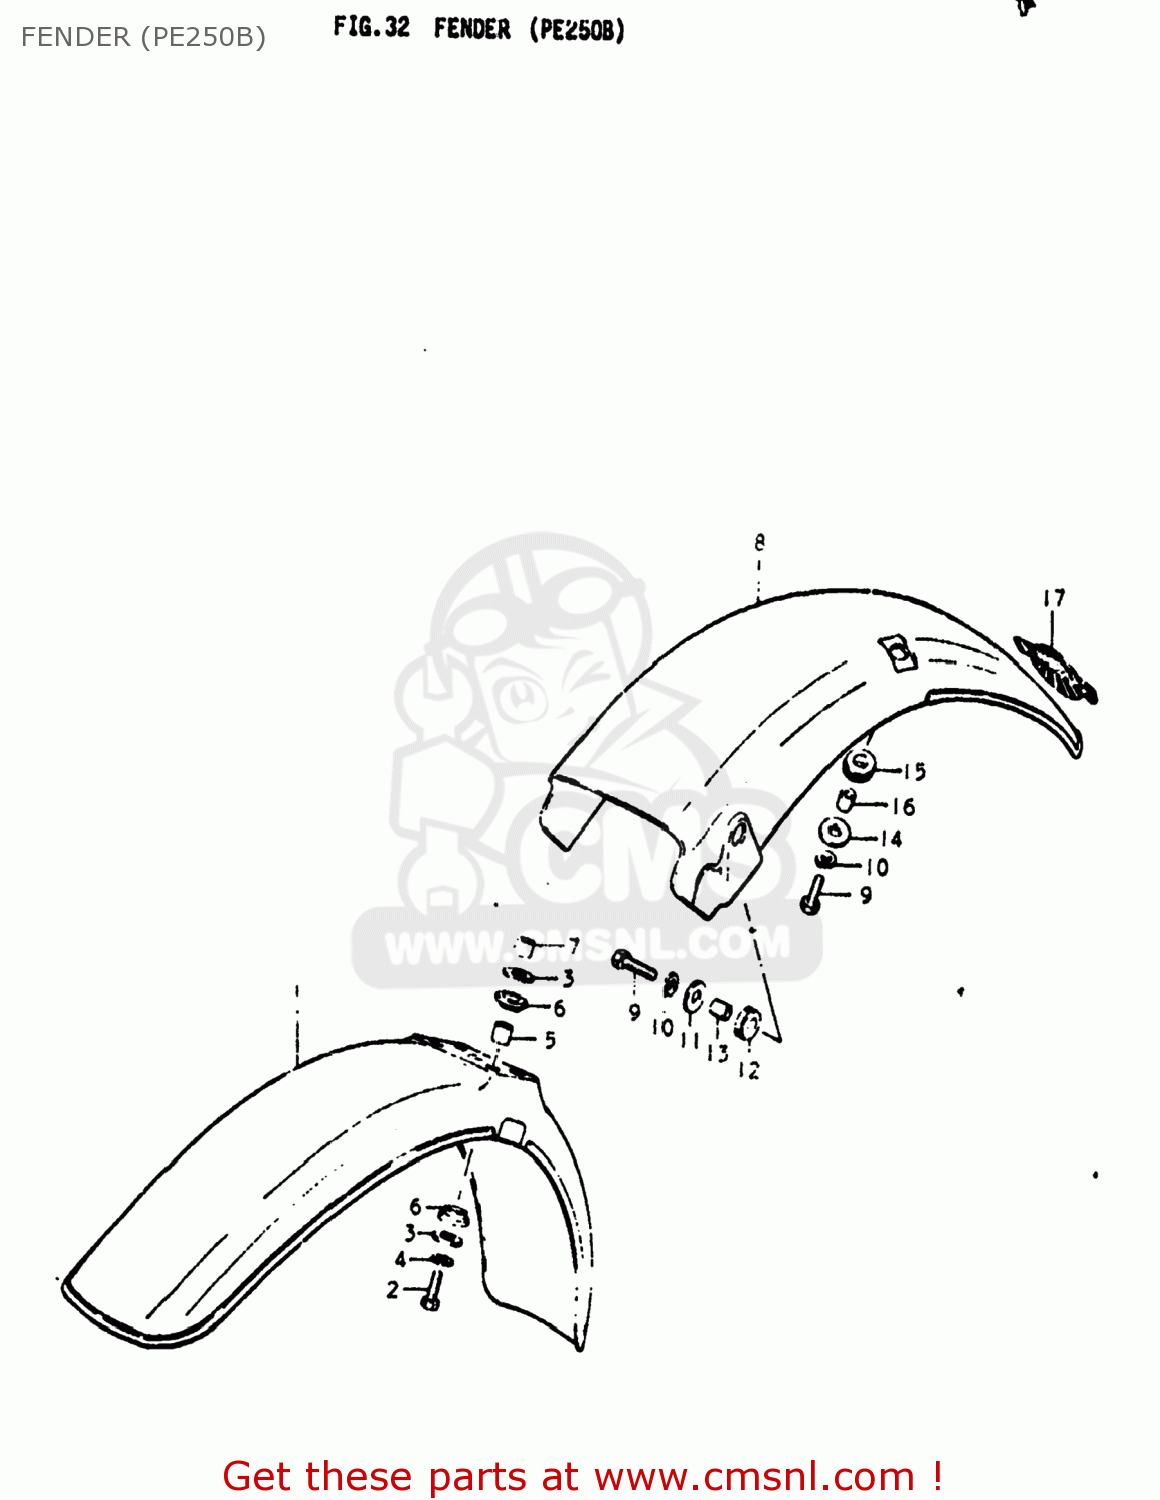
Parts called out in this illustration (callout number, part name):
1	FENDER,FRONT
2	BOLT
3	WASHER (6.5X20X1.2)
4	LOCK WASHER
5	SPACER (6.8X10X10)
6	CUSHION
7	SPACER
8	FENDER,REAR
9	BOLT
10	LOCK WASHER
11	WASHER (6.5X20X1.2)
12	CUSHION
13	SPACER(6.1X9X7.5)
14	WASHER (6.5X24X1.6)
15	CUSHION
16	SPACER
